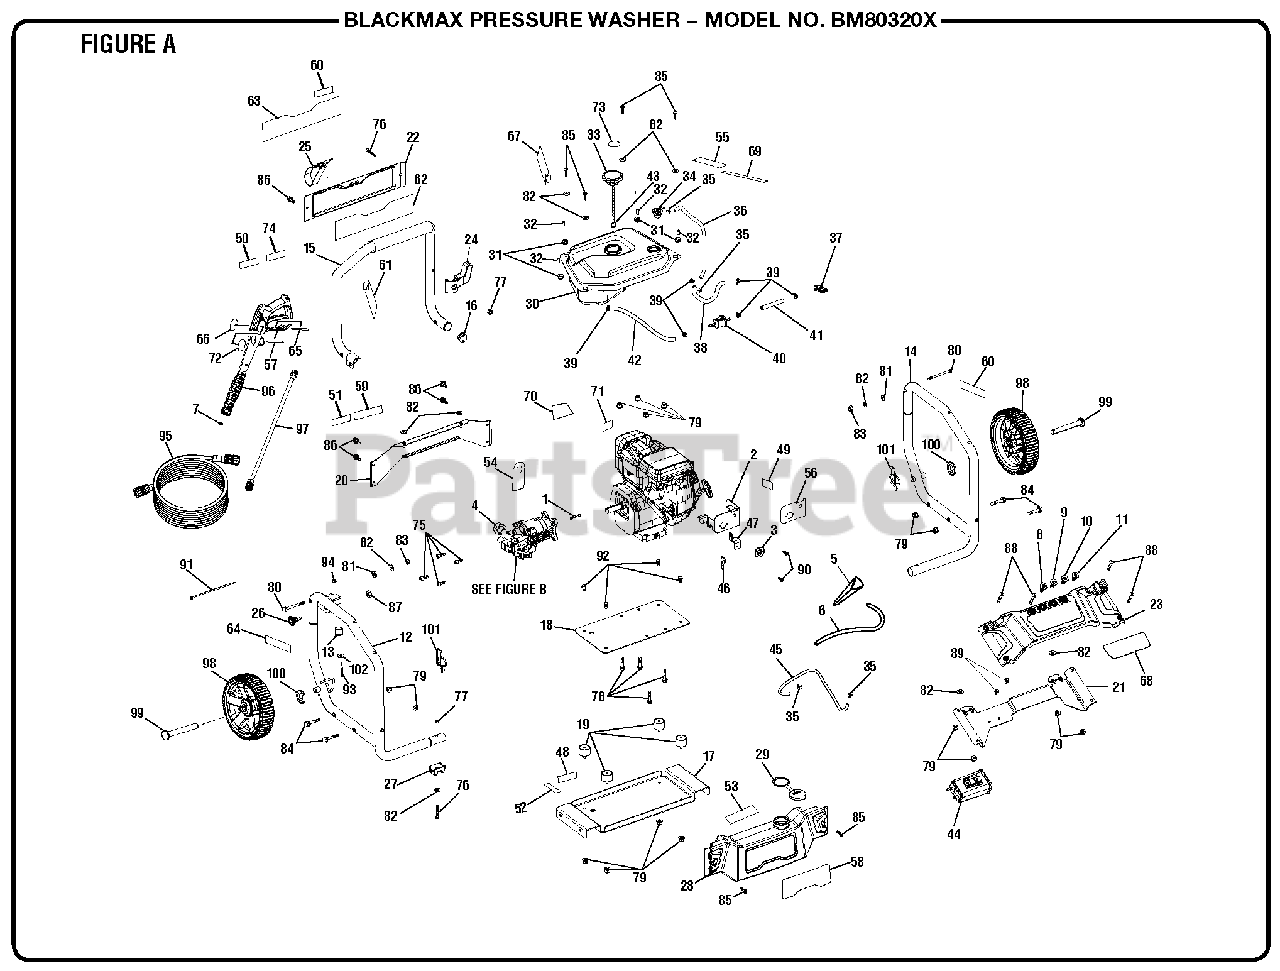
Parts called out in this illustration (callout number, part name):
1	Output Shaft Key
2	Fuel Valve Bracket
3	Fuel Valve Bezel
6	Chemical Siphon Tube
8	0deg Nozzle
9	25deg Nozzle
10	40deg Nozzle
11	Soap Nozzle (Blue)
12	Main Frame Assembly (Left)
13	Rubber Bumper
14	Main Frame Assembly (Right)
15	Handle Assembly
17	Engine Plate
18	Spacer Plate
20	Fuel Tank Support (Rear)
21	Fuel Tank Support (Front)
22	Hose Holder Panel
23	Faceplate Panel
24	Upper Wand Holder
25	Hose Holder Strap
26	Handle Lock Assembly
28	Soap Tank
29	Soap Tank Cap
30	Fuel Tank Assembly
31	Fuel Tank Bushing
32	Fuel Tank Bushing Insert
34	Vapor Vent
35	Hose Clamp (3/8 in.)
36	Vapor Hose (600 mm)
37	Fuel Valve
38	Fuel Hose (245 mm)
39	Hose Clamp (1/2 in.)
40	Fuel Filter
41	Fuel Hose (90 mm)
42	Fuel Hose (265 mm)
43	Ring Clip
44	Carbon Canister
45	Vapor Hose (425 mm)
46	Vapor Adapter
47	Vapor Adapter Bracket
48	Add Oil Label
49	Choke & Engine Switch Label
50	Combustion Label (English/Spanish)
51	Danger Label
52	Data Warnings Label (English/Spanish)
53	Soap Dilution Label
54	Oil Dipstick Hangtag
55	E85 Label
56	Fuel Valve Label
57	Trigger Handle Rating Label
58	Soap Tank Label
59	Hot Surface & Exhaust Label
60	Inquiries Label
61	Standard Nozzle Hangtag
62	Performance Label
63	Quick Start Label
64	Handle Release Label
65	Trigger Handle Warning Label (French/Spanish)
66	Black Max Wand Logo Label
67	Danger Hangtag
68	Black Max Logo Label
69	Extended Run Label
70	GC190 Label
71	Not For Sale In Ca Label
72	Trigger Handle Warning Label (English)
73	Remove Cap Fuel Stabilizer Label (English)
74	Remove Cap Fuel Stabilizer Label (Spanish)
75	Screw (5/16-24 x 23 mm, Cap Soc. Hd.)
76	Bolt (M6 x 48 mm, T30 Torx Pan Hd.)
77	Lock Nut (M6)
78	Bolt (M8 x 40 mm, Flange Hex Hd.)
79	Lock Nut (M8)
80	Connection Pin
82	Washer (1/4 in.)
83	Lock Nut (1/4-20 in.)
84	Bolt (M8 x 55 mm, Flange Hex Hd.)
85	Bolt (M6 x 25 mm,T30 Torx Pan Hd.)
86	Bolt (M6 x 16 mm, Flange Hex Hd.)
87	Nut (1/2-20 in.)
88	Bolt (M8 x 50 mm, Button Hd.)
89	Bolt (M6 x 12 mm, Flange Hex Hd.)
90	Bolt (M6 x 16 mm, Pan Hd.)
92	Bolt (M8 x 15 mm, Hex Hd.)
93	Bolt (M4 x 12 mm, Button Hd.)
94	Lock Nut (M4)
95	Hose (50 Ft.)
96	Trigger Handle
97	Wand Assembly
99	Wheel Axle
100	Washer (1/2 in.)
101	Wheel Axle Ring Clip
102	Washer (M4)
